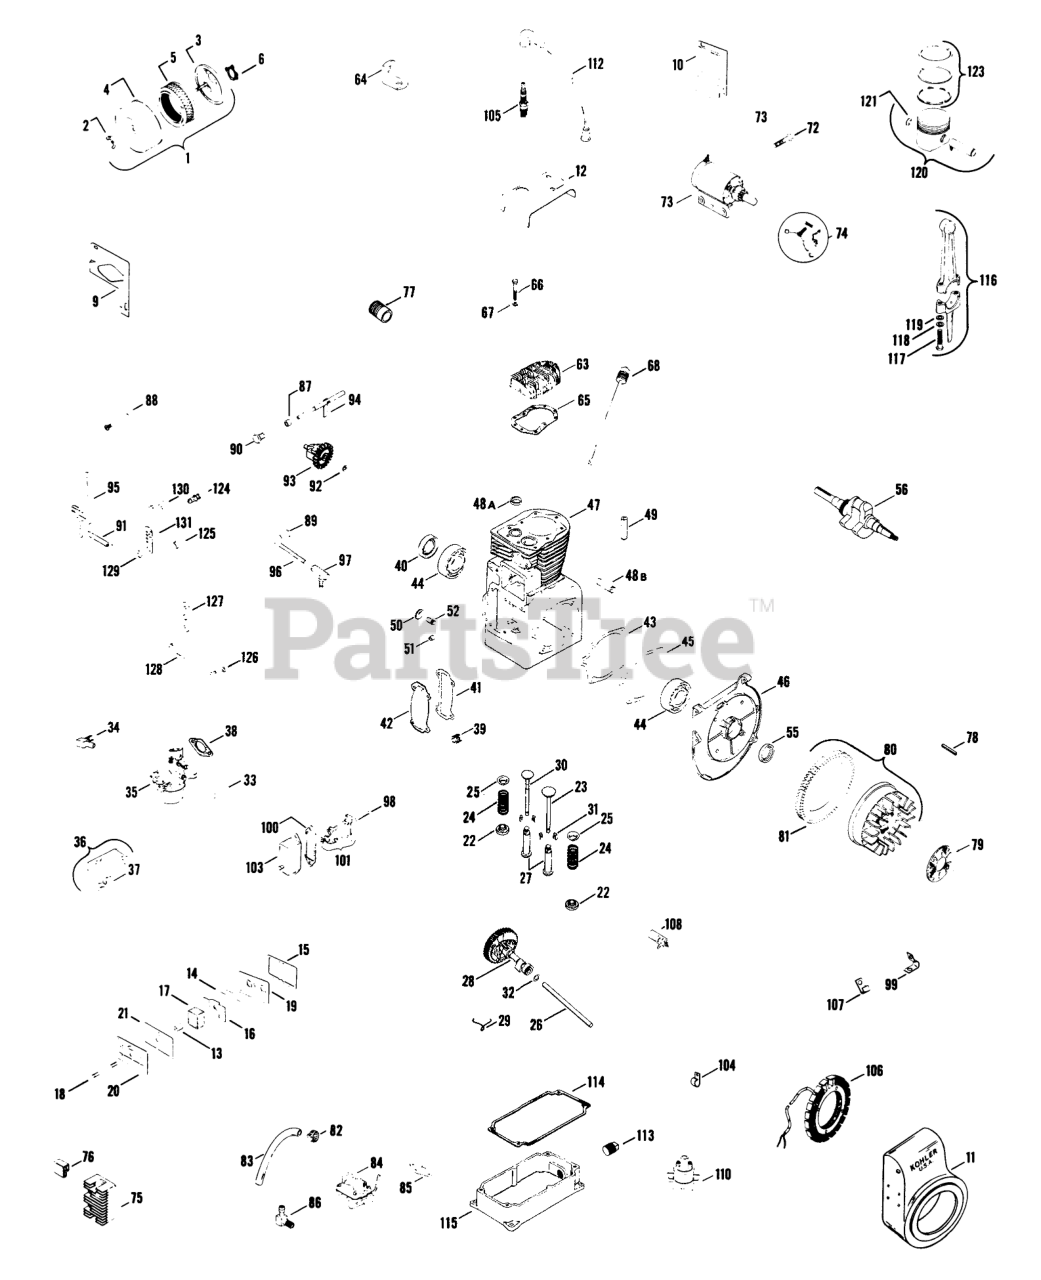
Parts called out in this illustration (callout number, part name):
1	Cleaner-Air Assembly
2	Nut-Wing
3	Base-Air Cleaner
4	Cover-Air Cleaner
5	Element
6	Gasket-Air Horn
9	BaffLe side air
10	Baffle cylinder
11	Housing-Blower
12	Baffle, head
13	Seal
14	Reed
15	Gasket
16	Baffle breather
17	Filter Breather
18	Stud, valve cover
19	Plate
20	Cover, valve
21	Gasket
22	Retainer-Spring
23	Valve-Intake
24	Spring
25	Retainer-Spring
26	Pin (Service)
27	Tappet
28	Camshaft-assembly
29	Spring-Actuating
30	Valve, exhaust
31	Keeper, Valve
32	Spacer
33	Screw sitd. hd.
34	Elbow
35	Carburetor-assembly
36	Bracket, choke
37	Clip
38	Gasket
39	Plug, Pipe
40	Seal rear oil
41	Gasket
42	Cover
43	Gasket
44	Ball Bearing
45	Gasket
46	Plate Bearing
47	Block, cylinder - assembly (Use A-237698 Miniblock)
48A	Insert
48B	Shaft
49	Guide Valve
50	Plug
51	Bearing
52	Shaft-Govemor
55	Seal, Front OiI
56	Crankshaft
63	Grease Fitting
64	Lift Cable
65	Gasket-Head
66	Screw
66	Screw-H.C.
67	Washer
68	Dipstick
72	Screw
73	Starter
74	Kit, Brush & Spring
75	Regulator
76	Connector
77	Nipple
78	Key
79	Screen grass
80	Flywheel-Assembly
81	Gear Ring
82	Clamp
83	Line Fuel
84	Pump, fuel
85	Gasket, pump
86	Elbow
87	Spacer
88	Pin-GovemorStop
89	Retainer Rod
90	Bushing
91	Spring-Governor
92	Washer
93	Gear, Governor
94	Shaft, Governor
95	Lever, Governor
96	Rod ball joint
97	Ball Joint
98	Rod, breaker
99	Clip
100	Gasket, Cover
101	Breaker
103	Cover breaker
104	Clip
105	Plug, spark
106	Stator
107	Clip
108	Condenser
110	Coil
112	Kit, Hi-Tension
113	Plug
114	Gasket
115	Base, oil pan
116	Rod, conn.-assembly (Std.)
117	Screw, connecting rod
118	Washer
119	Washer
120	Piston - assembly (Std.) (Includes pin & retainers)
121	Retainer
123	Ring set-Std. & 003 (Svc.)
124	Clamp, swivel wire
125	Spacer
126	Retainer, rod
127	Bell crank
128	Rod, throttle
129	Washer, tension
130	Bracket, adjusting screw
131	Bracket, speed control
